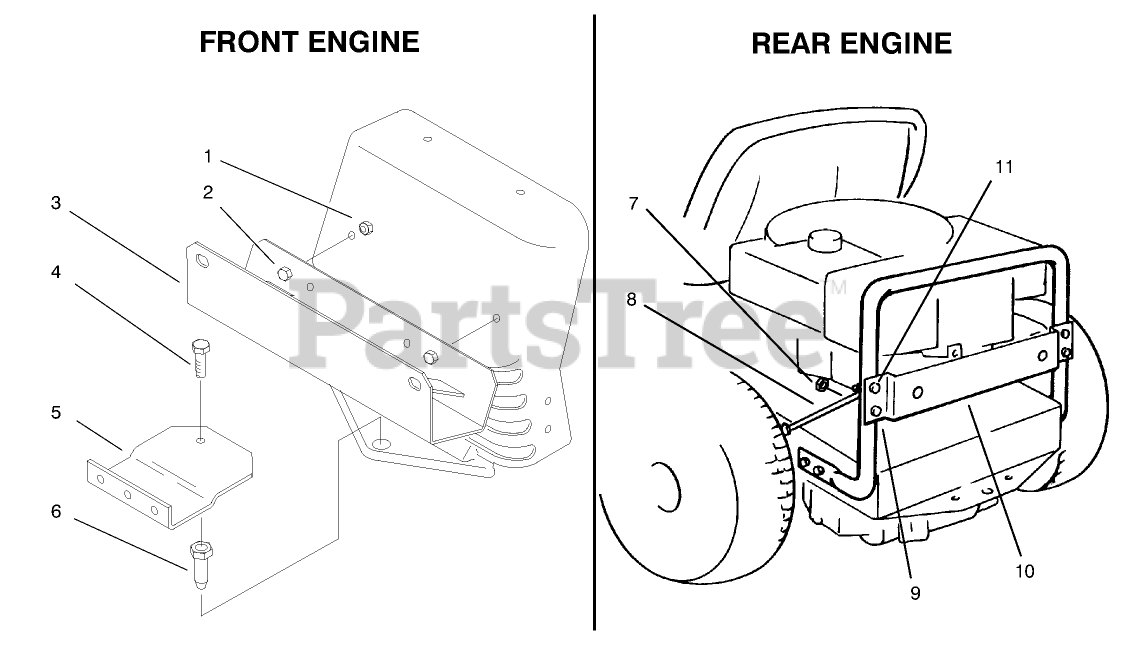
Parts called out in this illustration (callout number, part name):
1	NUT-LOCK, NI
2	SCREW-HH
4	SCREW-HH
6	PIN-MOUNTING, LOWER
7	NUT-LOCK, NI
8	BAGGING KIT BRACE
9	SCREW-HH
11	SCREW-HH
